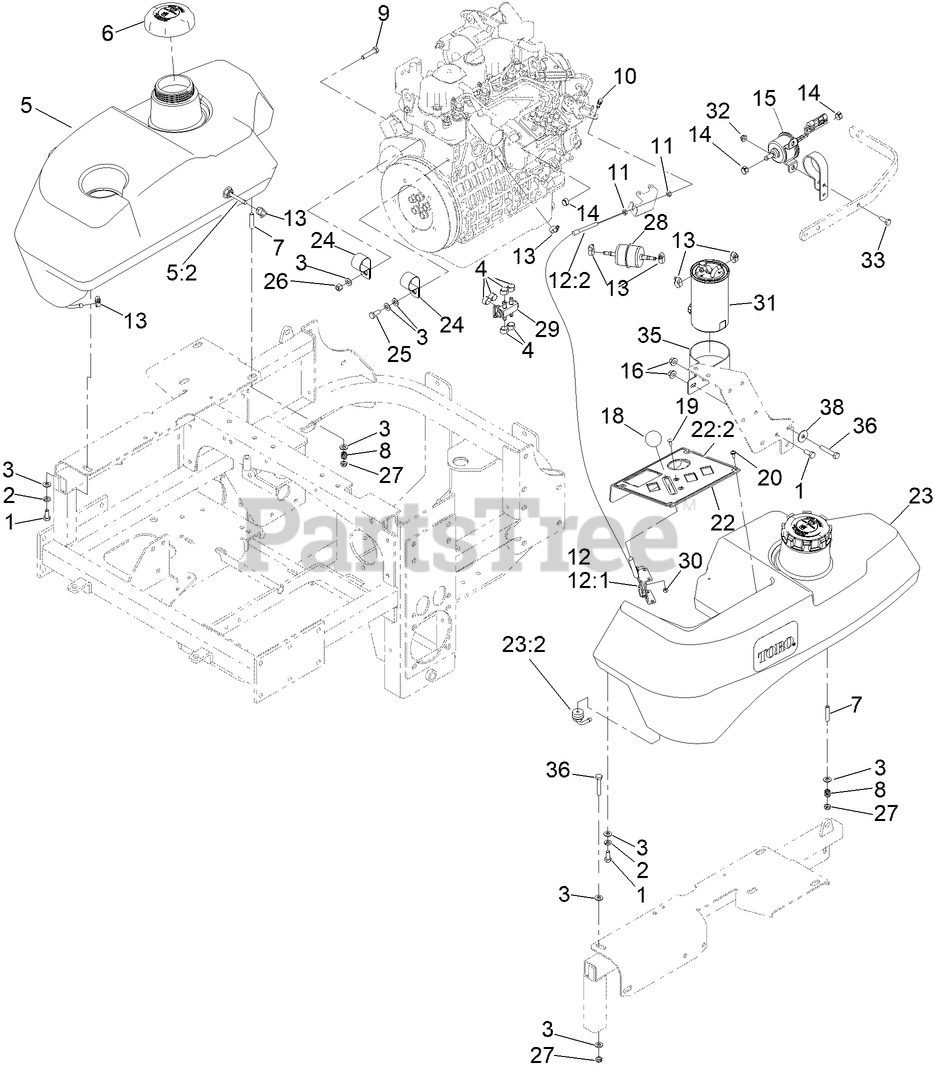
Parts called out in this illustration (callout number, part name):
1	SCREW-HH
2	WASHER-LOCK
3	WASHER-PLAIN
4	CLAMP-HOSE, FUEL
5	RH FUEL TANK ASM
5:2	FITTING-FUEL, BULKHEAD
6	CAP-BIODIESEL
8	SPRING-TANK, FUEL
9	SCREW-HH
10	SWIVEL-STOP, CABLE
11	NUT-JAM
12	CABLE-CONTROL, THROTTLE
12:1	LEVER-CABLE, THROTTLE
12:2	CABLE-THROTTLE
13	CLAMP-WORM
14	CLAMP-HOSE, FUEL
15	PUMP-FUEL, ELECTRIC
16	NUT-LOCK, NI
18	KNOB-BALL
19	BOLT-CARR
20	SCREW-PPH
22	CONTROL PANEL ASM
22:2	DECAL-PANEL, CONTROL
23	LH FUEL TANK ASM
23:2	FITTING-FUEL, BULKHEAD
24	CLIP-LOOM
25	SCREW-HH
26	NUT-LOCK, NI
27	NUT-LOCK, NI
28	FILTER-INLINE
29	VALVE-FUEL, DUAL FLOW
30	NUT-LOCK, NI
31	ELEMENT-FILTER, FUEL/WATER
32	NUT-HF
33	SCREW-HH
35	BRACKET-FILTER, FUEL
36	SCREW-HH
38	WASHER-FLAT
